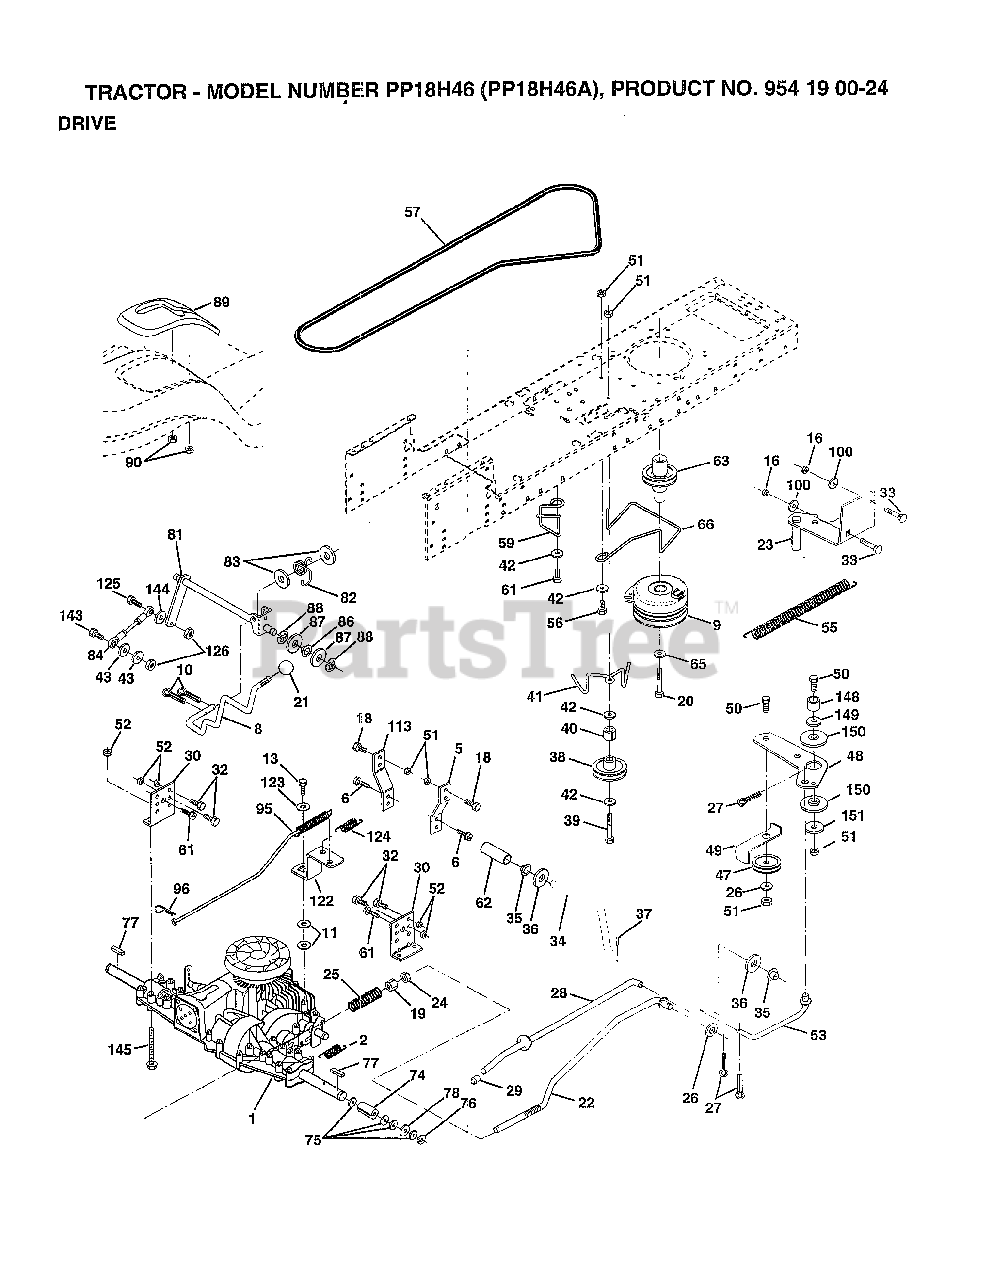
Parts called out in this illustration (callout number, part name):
2	SPRING.BRAKE.RETU
5	STRAP TORQUE
6	SCREW
8	"ROD SHIFT,FENDER"
9	CLUTCH.ELECTRIC
10	PIN COTTER 1/8
11	WASH-SHFT PLT LT
13	BOLT.1/4-28.W/PAT
16	NUT
18	BOLT
19	NUT
20	BOLT.7/16-20X4.25
21	KNOB.DUCKHEAD.1/2
22	BRAKE ROD
23	BRACKET.CLUT.MTG.
24	NUT
25	SPRING ROD LT
26	WASHER
27	COTTER PIN
28	ROD.BRAKE.PARK.LT
29	PLUNGER CAP T
30	TRANSAXLE MTG BKT
32	BOLT
33	BOLT
34	SHAFT ASM-PEDAL F
35	NYLON BEARING
36	WASHER LT
38	PULLEY.IDLER.FLAT
39	BOLT
40	SPACER T
42	WASHER
43	WASHER T
48	BELLCRANK.CLUTCH
49	RETAIN BELT
53	"LINK, CLUTCH T"
55	"SPRING, RETURN LT"
57	"V-BELT,GROUND DRV"
59	KEEPER BELT CNTSP
61	SCREW
62	PEDAL COVER T
63	PULLEY.ENGINE
65	LOCKWASHER
66	ENGINE BELT KEEPR
74	"SPACER AXLE,PVST"
75	WASHER
76	E-RING LT
77	SQUARE KEY
78	WASHER
81	SHAFT ASM CROSS
82	"SPRING,TORSION"
83	WASHER
84	"ROD TIE, PVST 20"""
86	BUSHING
87	WASHER D
88	KLIP RING
90	NUT
95	ROAD ASM BYPASS
100	WASHER M
113	"STRAP,TORQUE"
122	"PLATE-BYPASS,PVST"
123	WASHER
124	SPRING RETURN
143	BOLT
144	WASHER
145	BOLT.HEX.FLGHD
149	SPACER RETAINER
150	BUSHING.NYLON
151	WASHER
